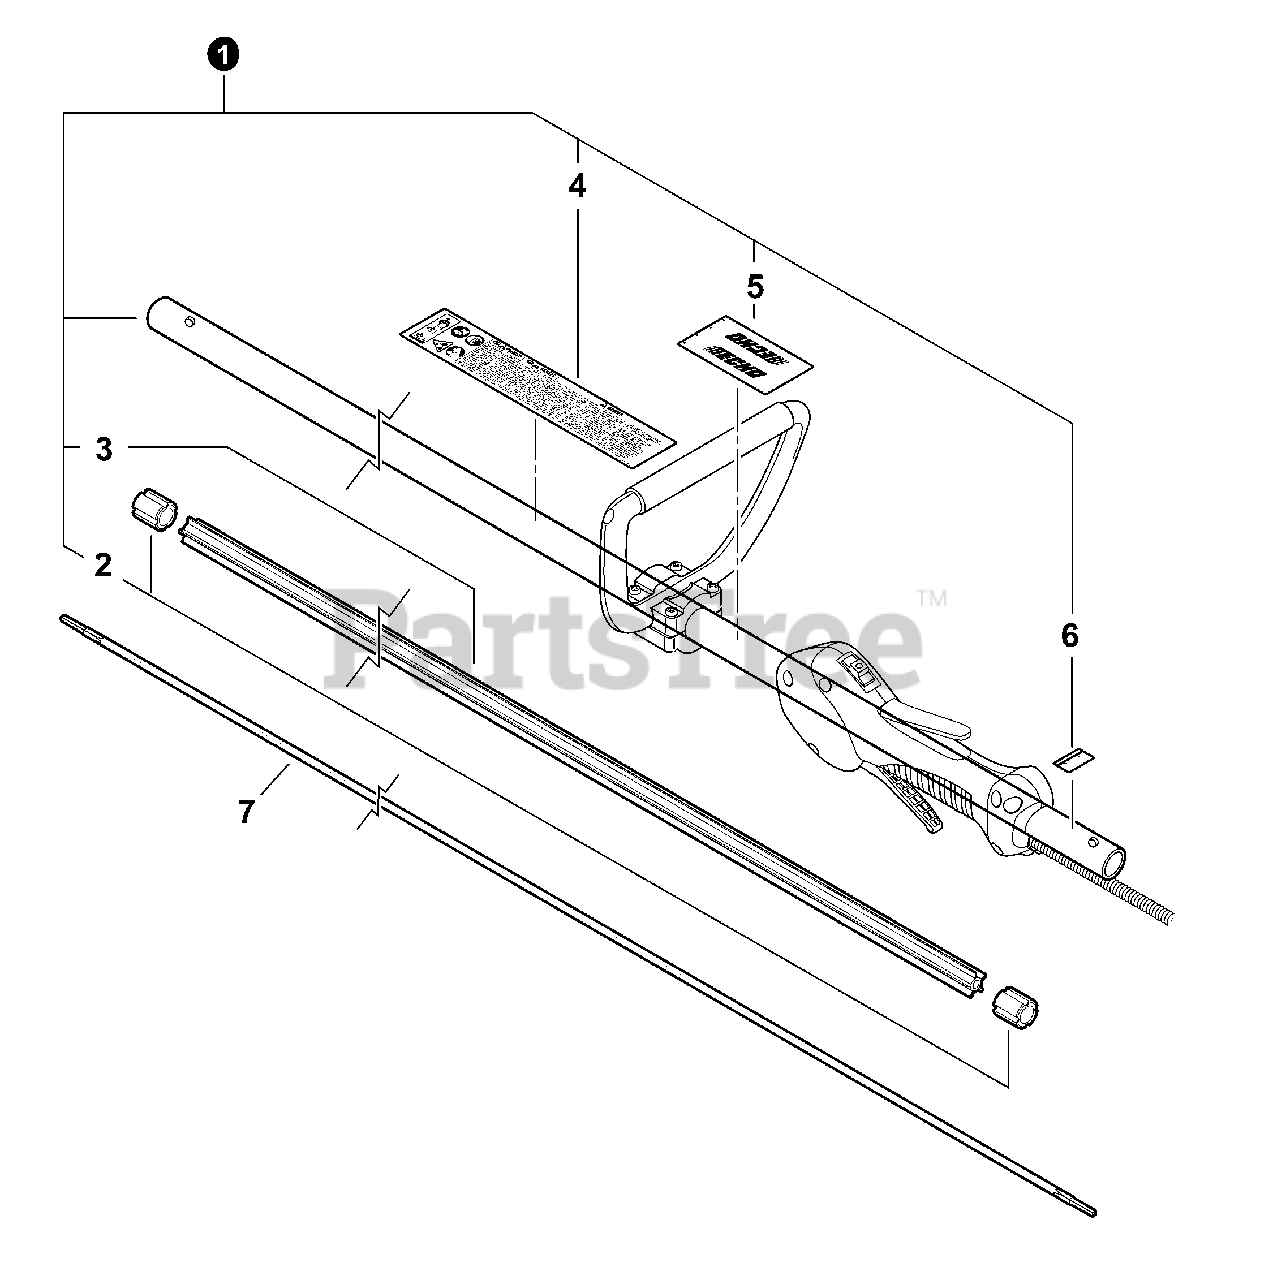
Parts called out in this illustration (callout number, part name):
1	MAIN PIPE ASY
3	LINER - FLEXIBLE
4	LABEL - CAUTION
5	LABEL - HANDLE LOCATION
6	LABEL - ALIGNMENT
7	DRIVESHAFT - FLEXIBLE
